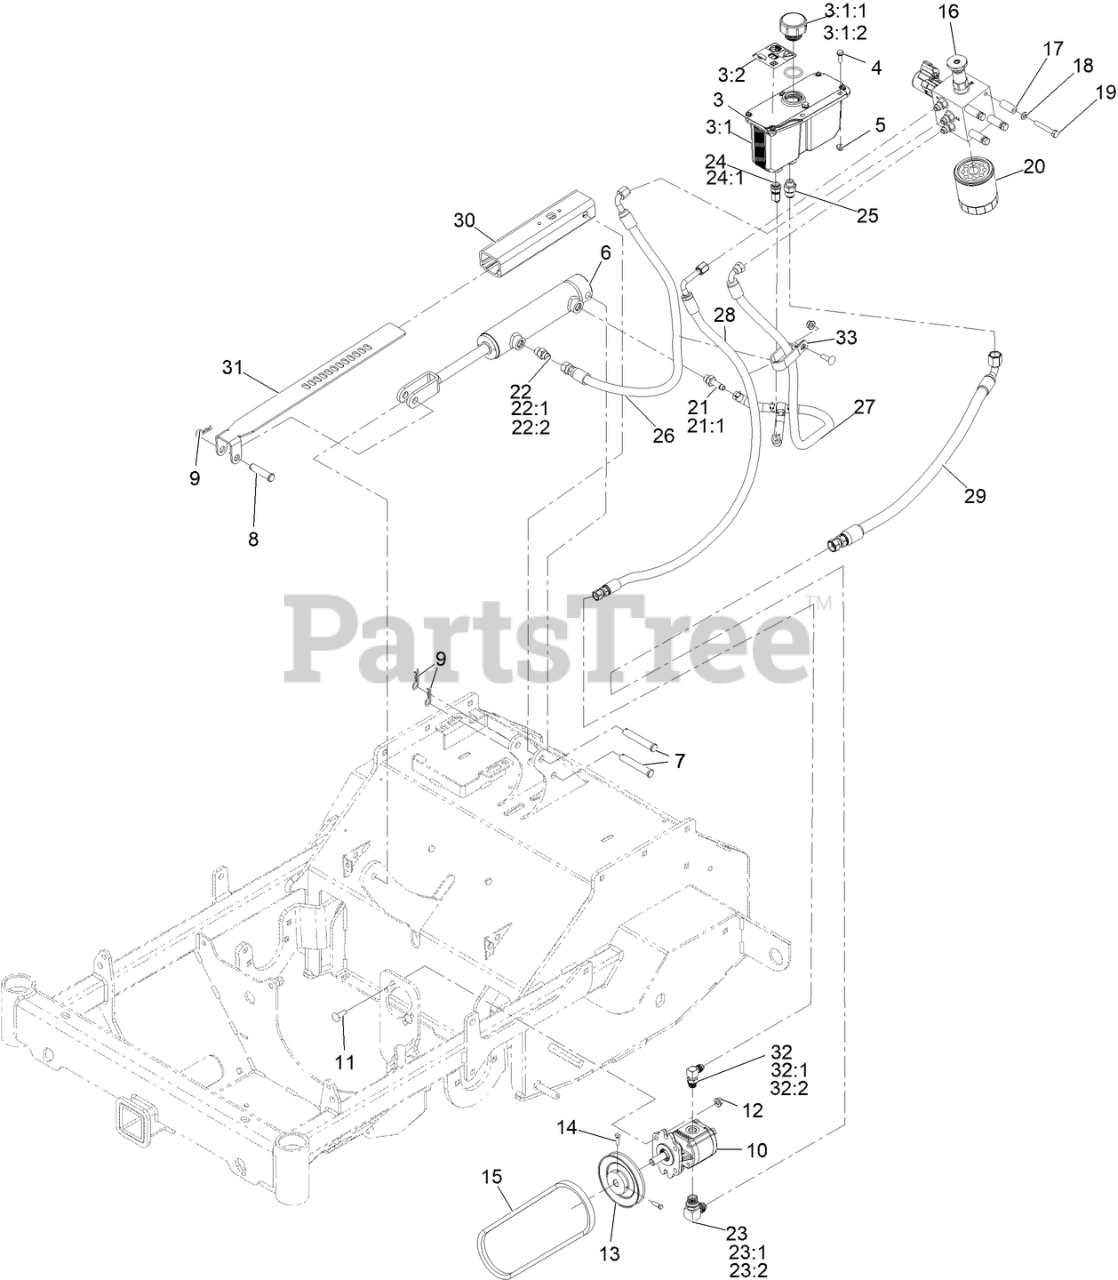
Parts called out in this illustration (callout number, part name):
3	RESERVOIR ASM
3:1	Reservoir-HYD
3:1:1	Cap-Reservoir, HYD
3:2	DECAL-WARNING
4	SCREW-HWH
6	CYLINDER-HYDRAULIC
7	PIN-CLEVIS
8	PIN-CLEVIS
9	PIN-HAIR
10	PUMP-HYDRAULIC
11	SCREW-CARR
12	NUT-HF, NI
14	SCREW-SQH
16	MANIFOLD ASM
18	WASHER-LOCK
19	SCREW-HH
20	FILTER-25 MICRON, BI-DIRECTIONAL
21	ADAPTER-STRAIGHT
21:1	O-RING
22	FITTING-STRAIGHT
22:1	BOSS O-RING
23	FITTING-90 DEG
24	FITTING-BARBED, 45 DEG
24:1	O-RING
25	FITTING-STR
26	HYDRAULIC HOSE ASM
27	HYDRAULIC HOSE ASM
28	HYDRAULIC HOSE ASM
29	HYDRAULIC HOSE ASM
30	HOUSING-DEPTH CONTROL
31	BRACKET-DEPTH CONTROL
32	FITTING-90 DEG
32:1	BOSS O-RING
33	Clamp-R, Double
